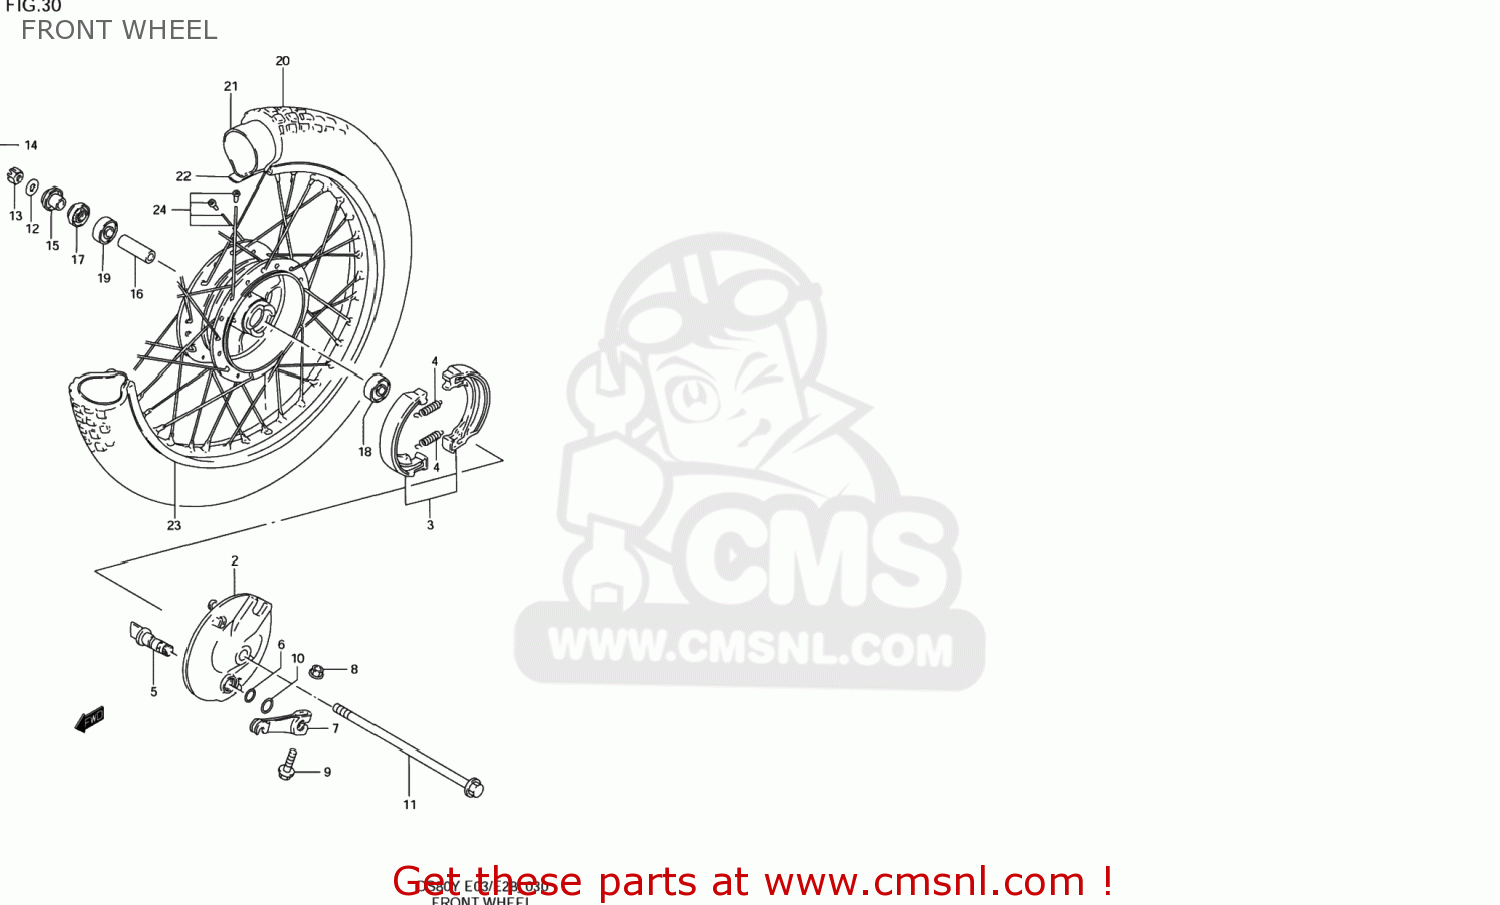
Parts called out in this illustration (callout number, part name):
1	HUB,FR
2	PANEL,FR BRAKE ANCHOR
3	SHOE SET,BRAKE (NAS)
4	SPRING(L:35.8)
5	CAM,FR BRAKE
6	O RING(D:2.5,ID:13.8)
7	LEVER,FR BRAKE CAM
8	NUT
9	BOLT
10	WASHER(14.5X22X1.6)
11	AXLE,FR
12	WASHER (10X20X2.3)
13	NUT
14	PIN 20X20
15	SPACER,FR AXLE,R
16	SPACER(10.1X16X51)
17	SEAL,OIL(15X31X5)
18	BEARING
19	BEARING
20	TIRE(2.25 14)
21	TUBE,INNER
22	PROTECTOR,INNER TUBE
23	RIM,FR WHEEL(1.40X14)
24	SPOKE SET,FR WHEEL
